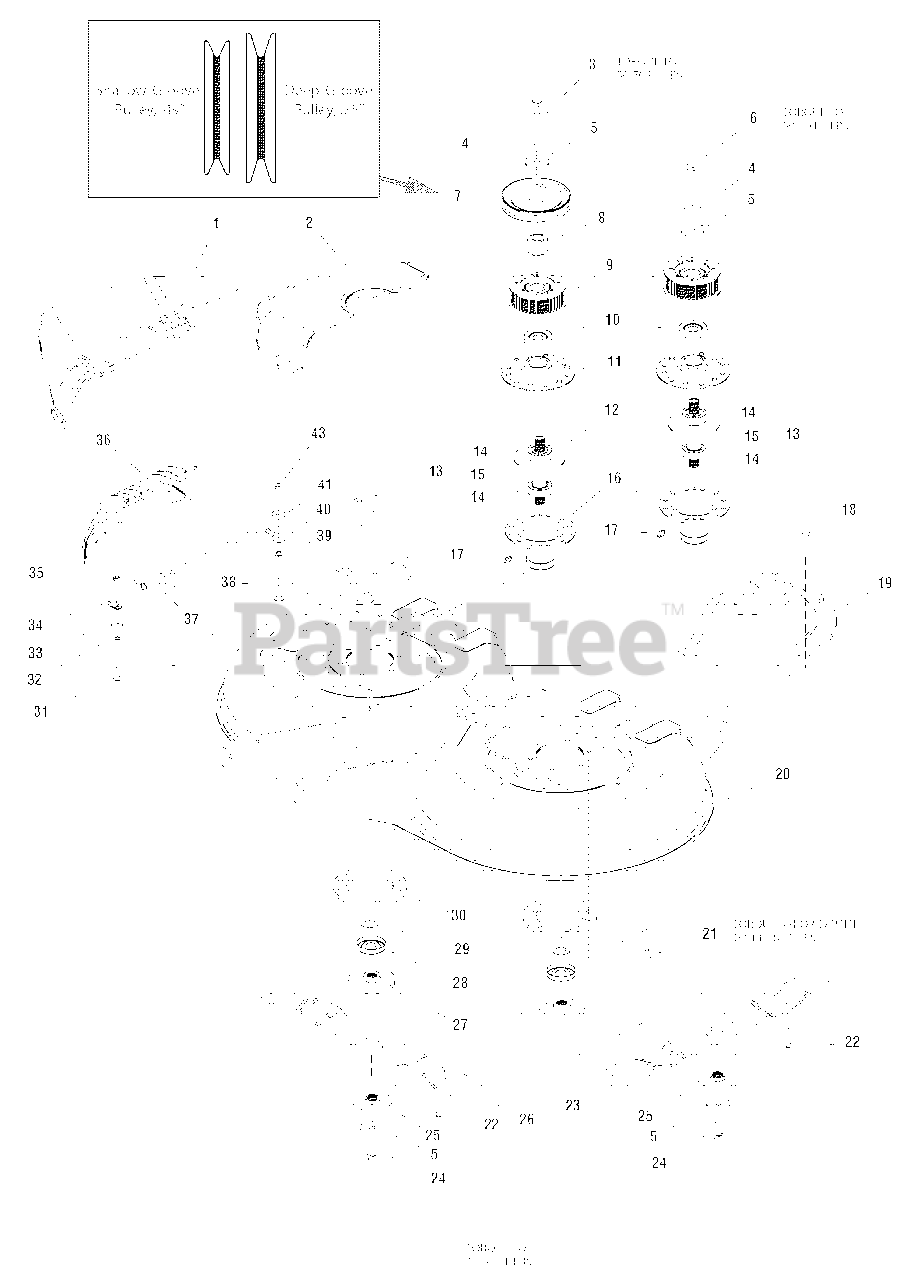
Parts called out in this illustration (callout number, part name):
1	DEFLECTOR, Discharge
2	COVER, Arbor RH Black
3	CAPSCREW, Hex Flange, 7/16-14 x 3-1/2 G8
4	WASHER
5	WASHER, Spring
6	CAPSCREW, 7/16-14 x 2-3/4 G8
7	PULLEY, Drive, Shallow-Groove, .49"
9	SPROCKET & FLANGE ASSEMBLY, Riveted, 38 Tooth
10	SHIELD, Bearing Upper, Arbor
11	COVER, Arbor Housing
12	GASKET, Foam
13	ARBOR SHAFT & BEARINGS ASSEMBLY
14	BEARING, Upper
15	SHAFT, Spline 5.389LG
16	HOUSING, Arbor Bottom
17	FITTING, Grease
18	CAPSCREW, Hex Head, Taptite, 5/16-18 x 3/4
19	COVER, Arbor, LH
20	HOUSING ASSEMBLY, 40" Mulcher Orange
21	CAPSCREW, Taptite Hex Washer Head, 5/16-18 x 1
22	PIN, Blade
23	BLADE, Mower 40" Mower LH
24	CAPSCREW, Hex Head, 7/16-14 x 2-1/4 G8
25	WASHER, Spline
26	BLADE, Mower 40" Mower RH
27	ADAPTOR, Blade
28	SHIELD, Bearing
29	WASHER, Shim
30	ADAPTOR, Arbor
31	CARRIAGE BOLT, 1/4-20 x 7/8
32	NUT, Push On
33	WASHER, Plain, 1/4 (6 Total for Export)
34	CLAMP
35	NUT, Hex, 1/4-20
36	DOOR, Mulching, Black Plastic
37	SPRING
38	CARRIAGE BOLT, 5/16-18 x 1
39	NUT, Push
40	ROD, Pivot
41	WASHER, Plain, 5/16
43	NUT, Hex ESNA 5/16-18
